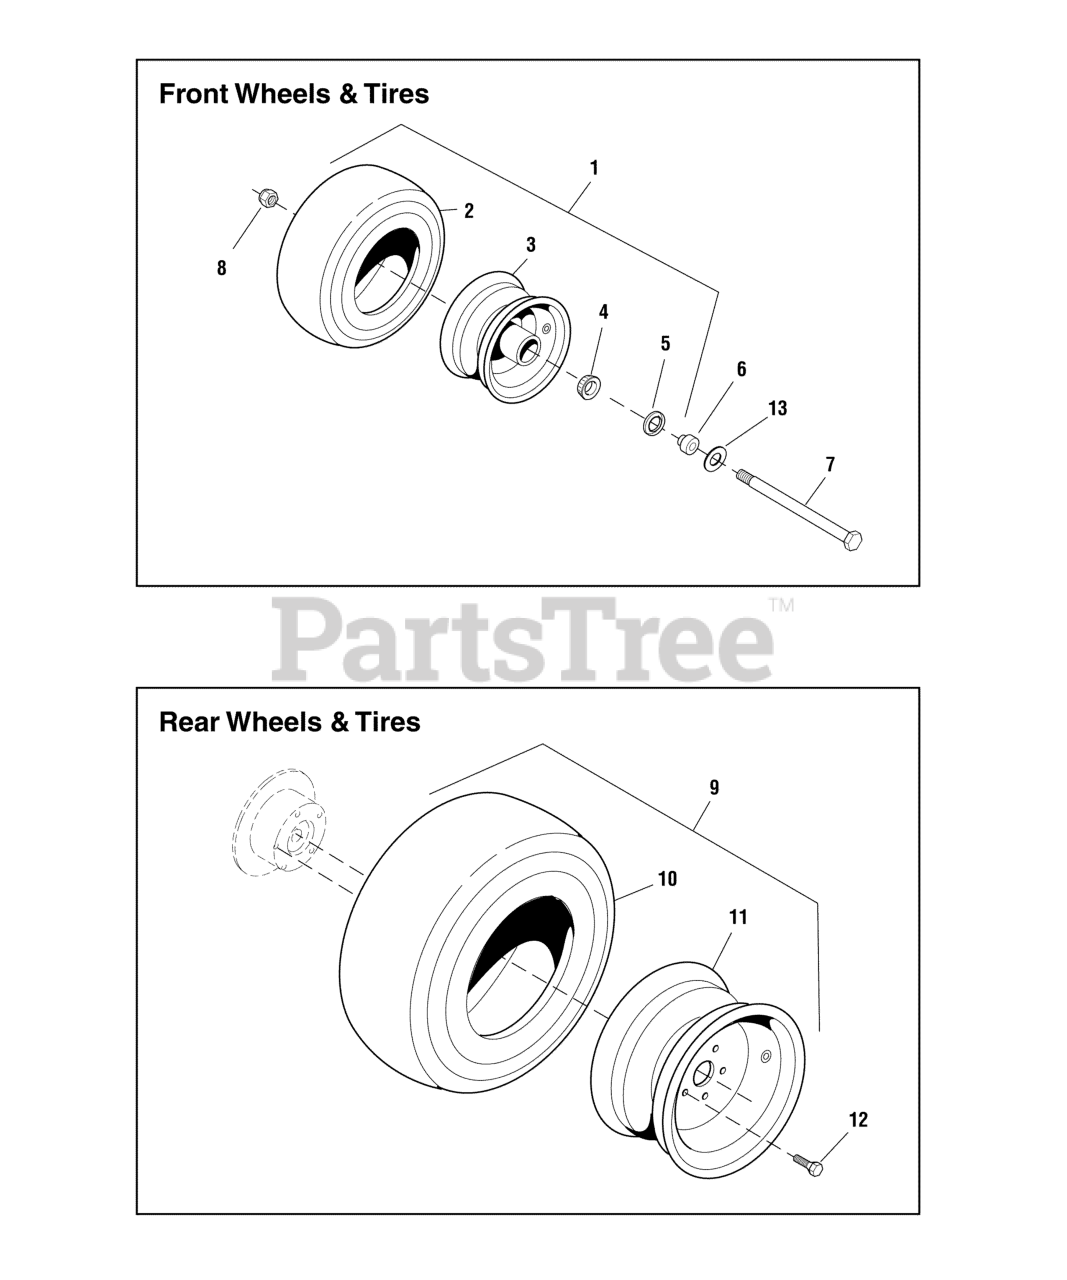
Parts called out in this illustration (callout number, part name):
1	TIRE ASSM, 13 X 6.5 - 6, PNE / TB
1	TIRE ASSM, 13 X 6.5 - 6, FF / TB
2	TIRE, RUBBER ONLY
3	WHEEL ASSEMBLY, for 13 x 6.5 - 6 Tires, COMPLETE
4	BEARING, Tapered Roller
5	SEAL, GREASE
6	ADAPTER, CASTER AXLE, CZ
7	BOLT, 1/2-13 X 9" GD5 YZ
8	NUT, Hex Flange, Nylock, 1/2-13
9	TIRE WHEEL ASM, 24X12.00-12, TURF MASTER
10	TIRE, 24 X 12 X 12
11	WHEEL, 12 X 8.5
12	BOLT, WHEEL LUG, 1/2" X 1-5/8
13	WASHER, 1/2 SAE
